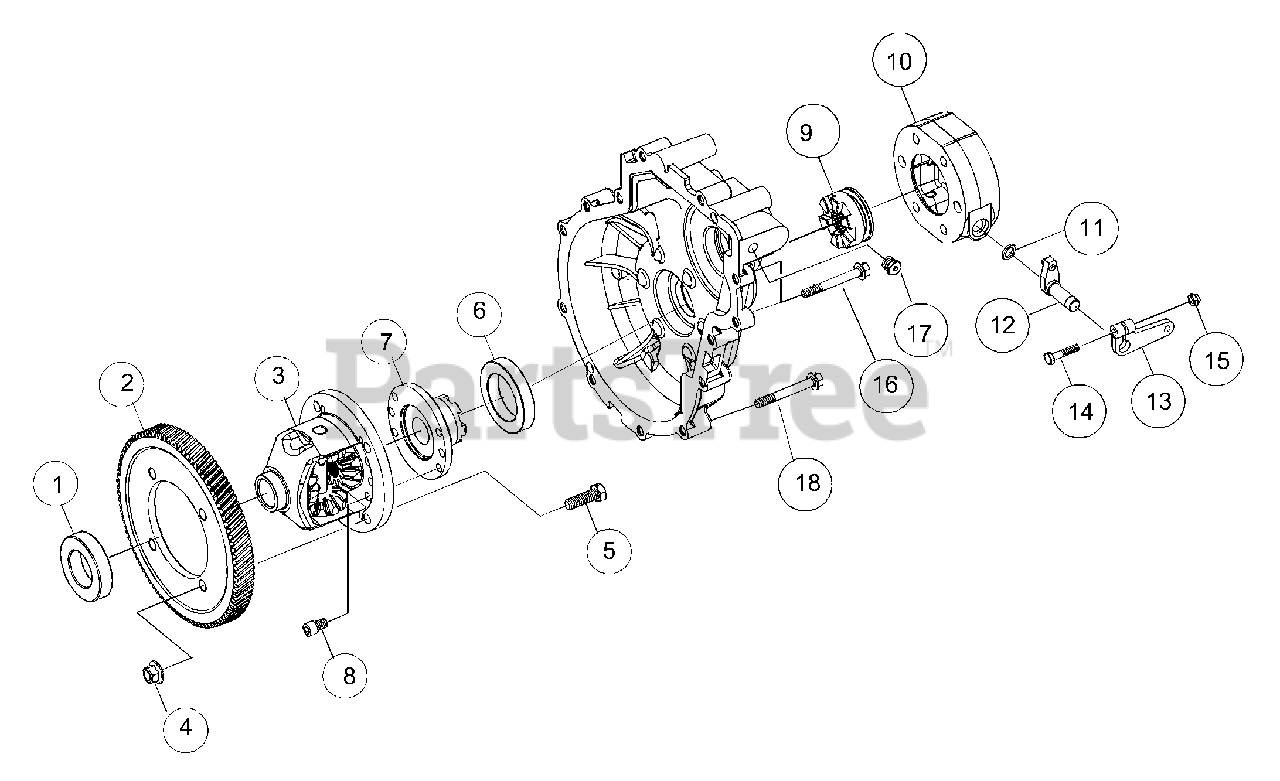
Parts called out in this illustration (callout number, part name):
1	Bearing, Ball
2	Gear, Helical (Ring)
3	Assembly, Differential
6	Bearing, Ball
7	Flange, Half, Differential
8	Screw, Socket Head
9	Gear, Clutch Differential Lock
10	Housing, Differential Lock
12	Assembly, Shift Shaft
13	Lever, Actuating
14	Screw, Hex Head
16	Screw, Flange Head
18	Screw, Flange Head
